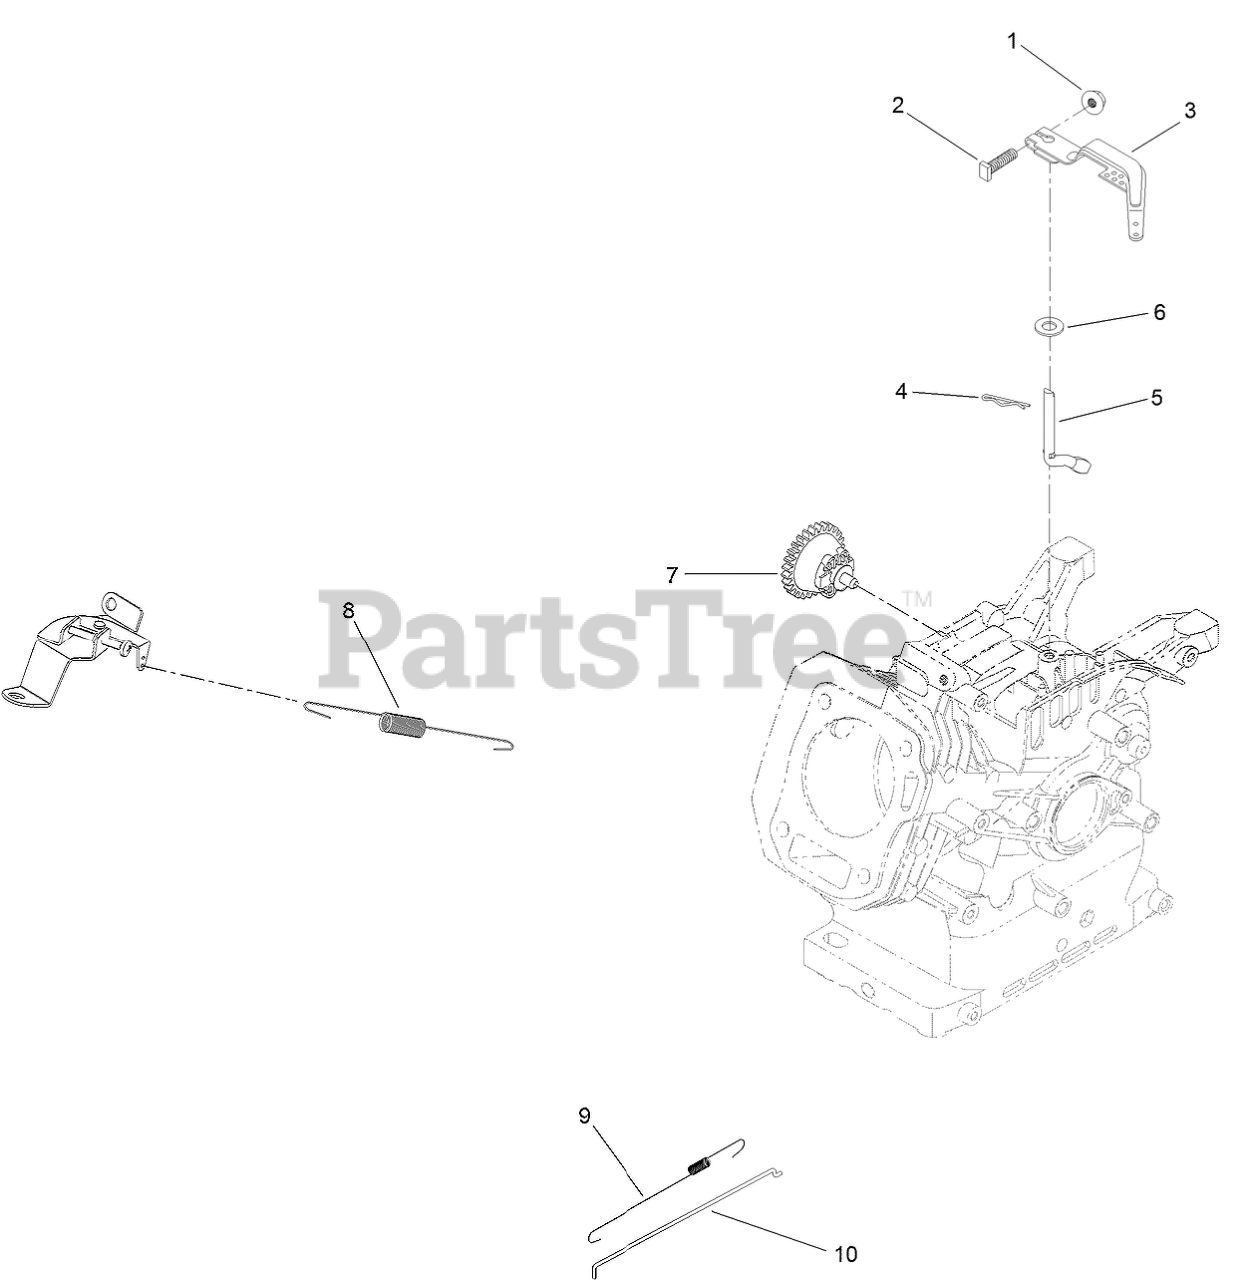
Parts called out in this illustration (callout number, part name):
1	NUT-FLANGE
2	BOLT-ARM, GOVERNOR
3	ARM-GOVERNOR
4	PIN-HAIR
5	SHAFT-GOVERNOR
6	WASHER-PLAIN
7	GOVERNOR GEAR ASM
8	SPRING-GOVERNOR
9	SPRING-RETURN, THROTTLE
10	ROD-GOVERNOR
